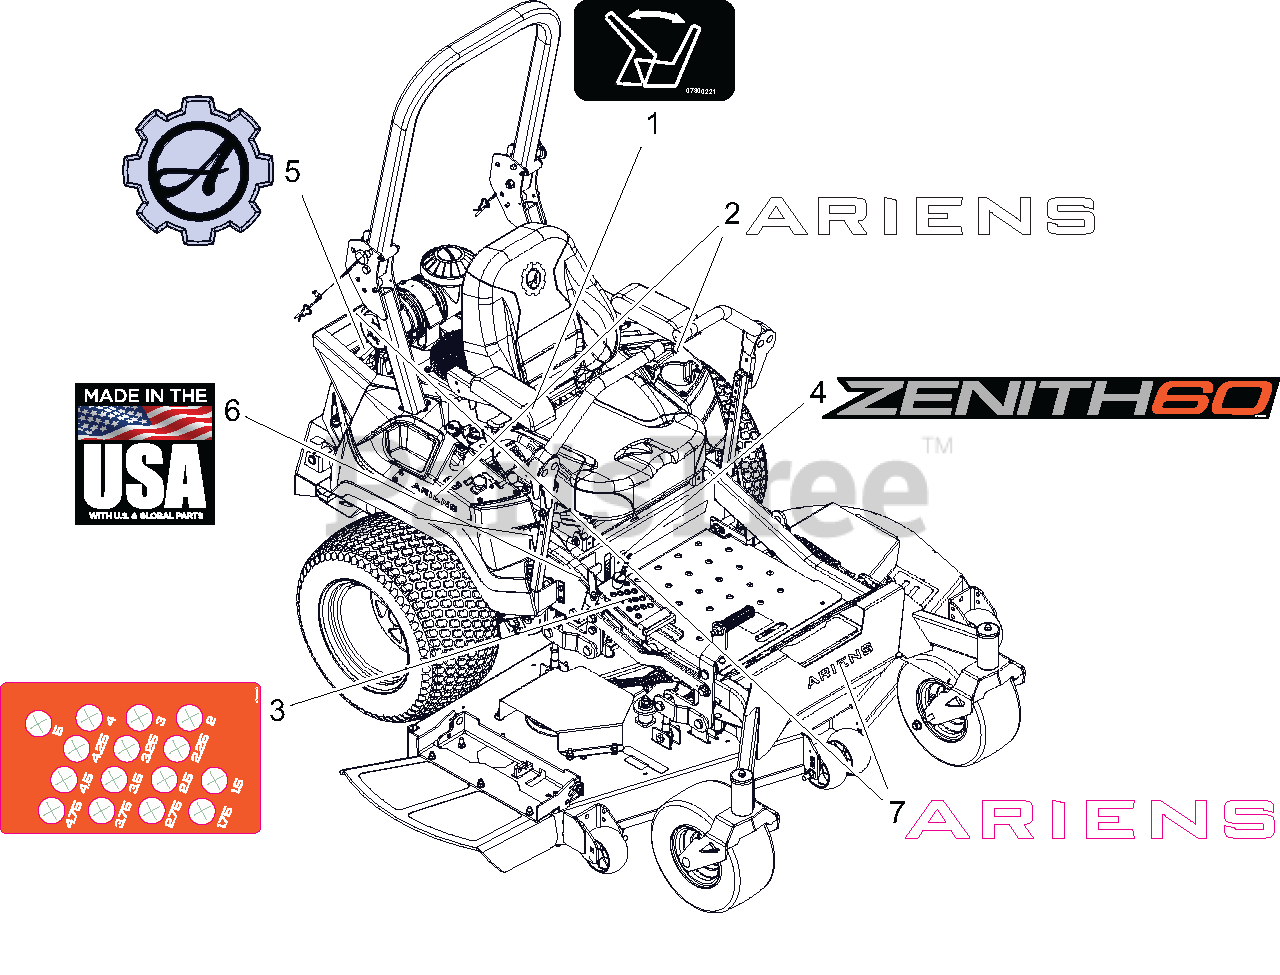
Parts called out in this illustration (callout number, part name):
1	DECAL - SEAT RELEASE
2	DECAL, ARIENS (6.50")
3	DECAL, ARIENS HOC
4	DECAL, ZENITH 60
5	DECAL- ARIENS GEAR BADGE
5	DECAL, MADE IN USA
7	DECAL - ARIENS 9.625"
